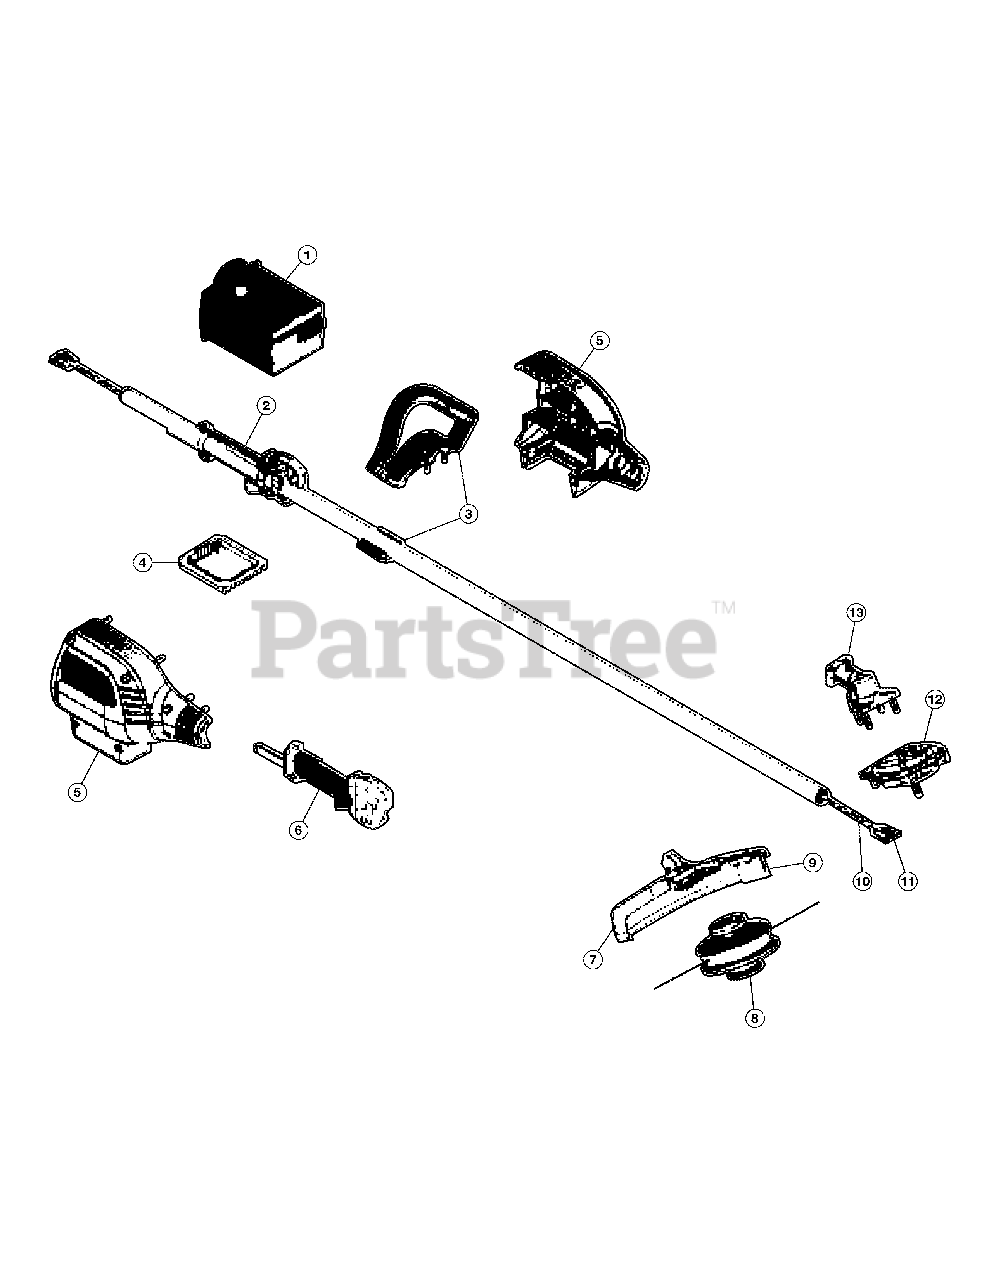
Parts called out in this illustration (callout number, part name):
1	Power Sleeve Assembly
2	Trimmer Shaft Assembly
3	Assist Handle Assembly
4	Controller PCB Assembly
5	Power Housing Assembly
6	Grip Handle Assembly with Switch Wires
7	String Guard Assembly
8	Weedwrap Bumphead
10	Phase Wire Assembly
11	Hall Wire Assembly
12	Motor Assembly
